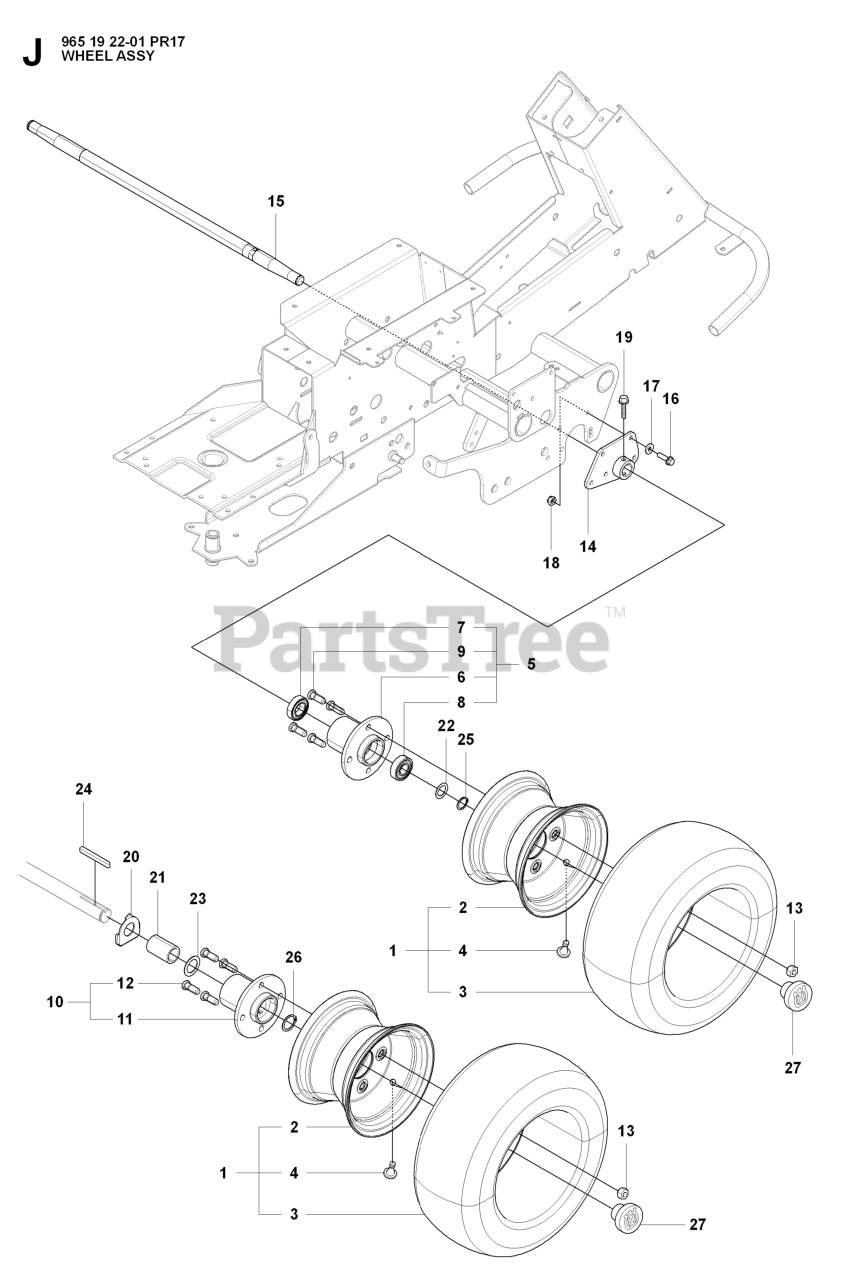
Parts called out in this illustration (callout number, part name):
4	VALVE
7	Ball Bearing 6005-2rs
8	BALL-BEARING 6204-2RS
16	BOLT
17	WASHER BRB 8.4X17
18	LOCKNUT M8
19	BOLT FLANGE - M8X40\
20	WASHER STEEL
25	RETAINING RING SGA 20
26	RETAINING RING SGA 25
